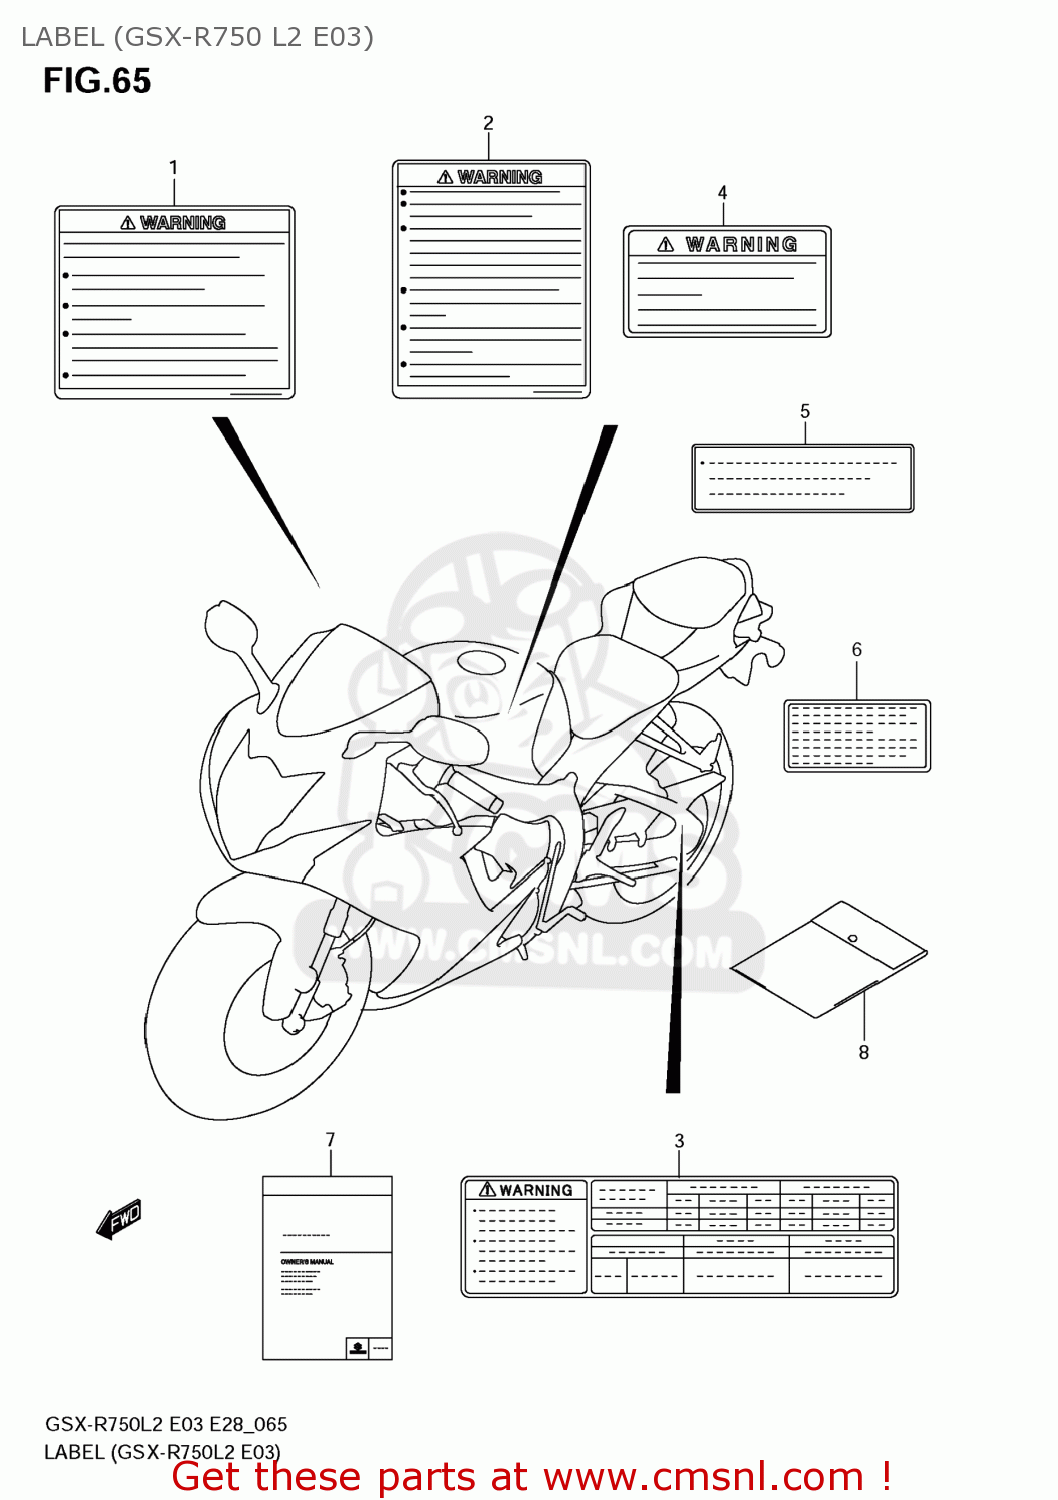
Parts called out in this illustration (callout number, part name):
1	LABEL,GENERAL WARNING
2	LABEL,SCREEN
3	LABEL,TIRE INFORMATION
4	LABEL,WARNING STEERING
5	LABEL,FUEL INFORMATION
6	LABEL,MANUAL NOTICE
7	MANUAL,OWNER'S
8	BAG,OWNER'S MANUAL
